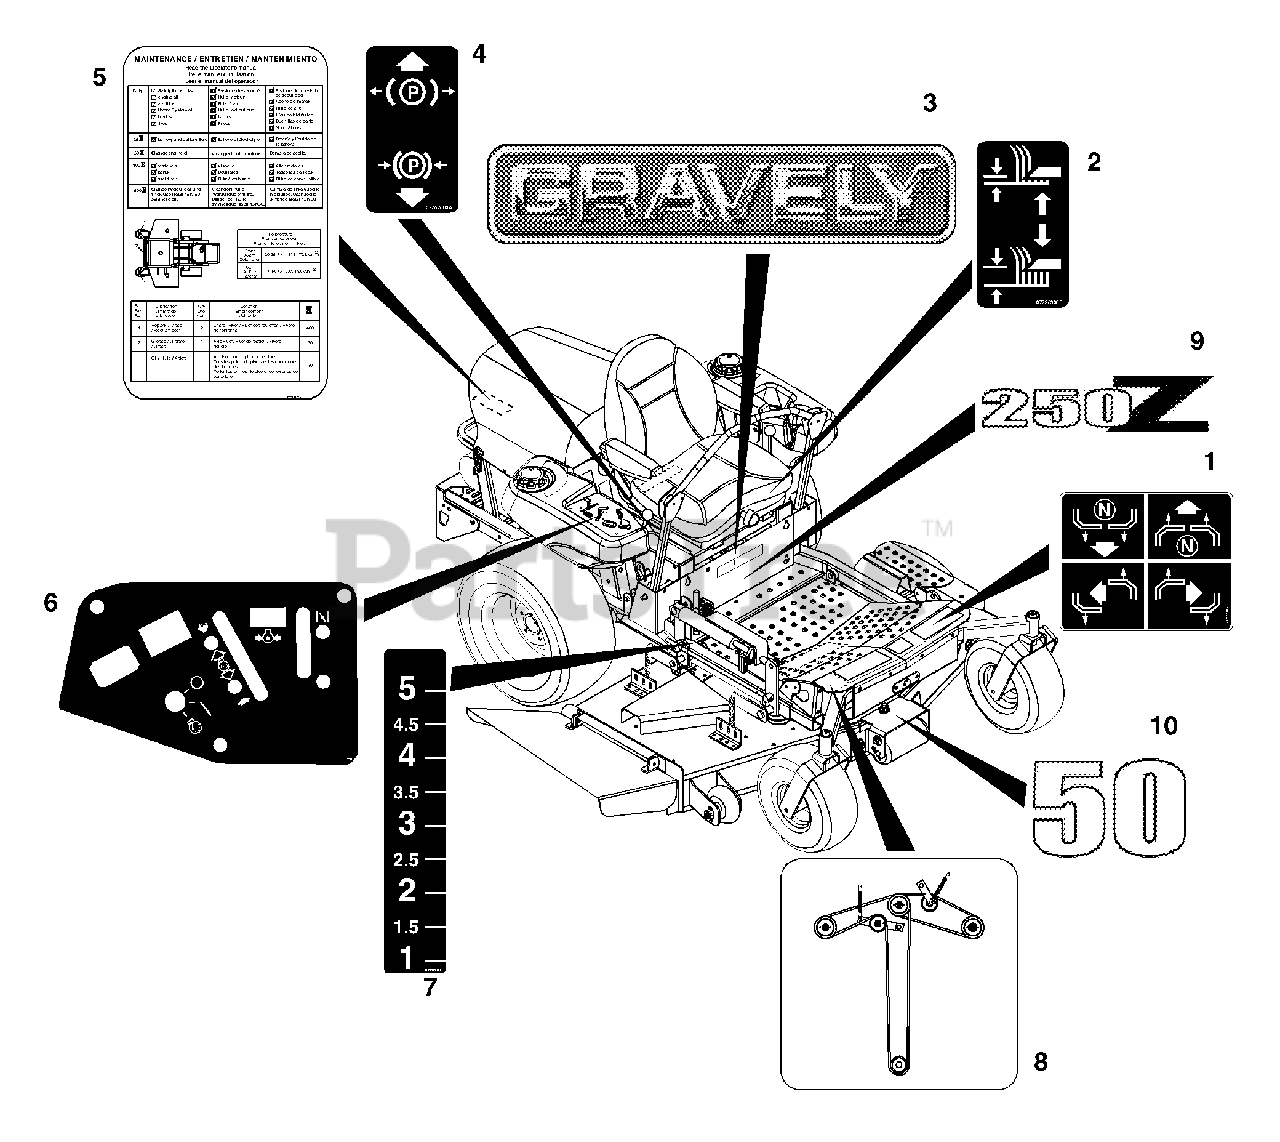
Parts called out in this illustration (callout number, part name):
1	Decal-Instructional Steering
2	Decal, Lift Lever
3	Decal, 15" Gravely Logo
4	Decal, Parking Brake Lever
5	Decal, Service Instructions
6	Decal, Control Panel
6	Decal, Control Panel-EFI
7	Decal, Height of Cut
8	Decal, Belt Diagram (020, 029, 033, 034, 035)
8	Decal, Belt Diagram (030, 032)
9	Decal, Logo- Gravely 250Z (030, 032)
9	Decal, PM-260Z (020, 029, 033)
9	Decal, PM-272Z (034, 035)
10	Decal, 50 (030, 032)
10	Decal, 60 (020, 029, 033)
10	Decal, 72 (034, 035)
